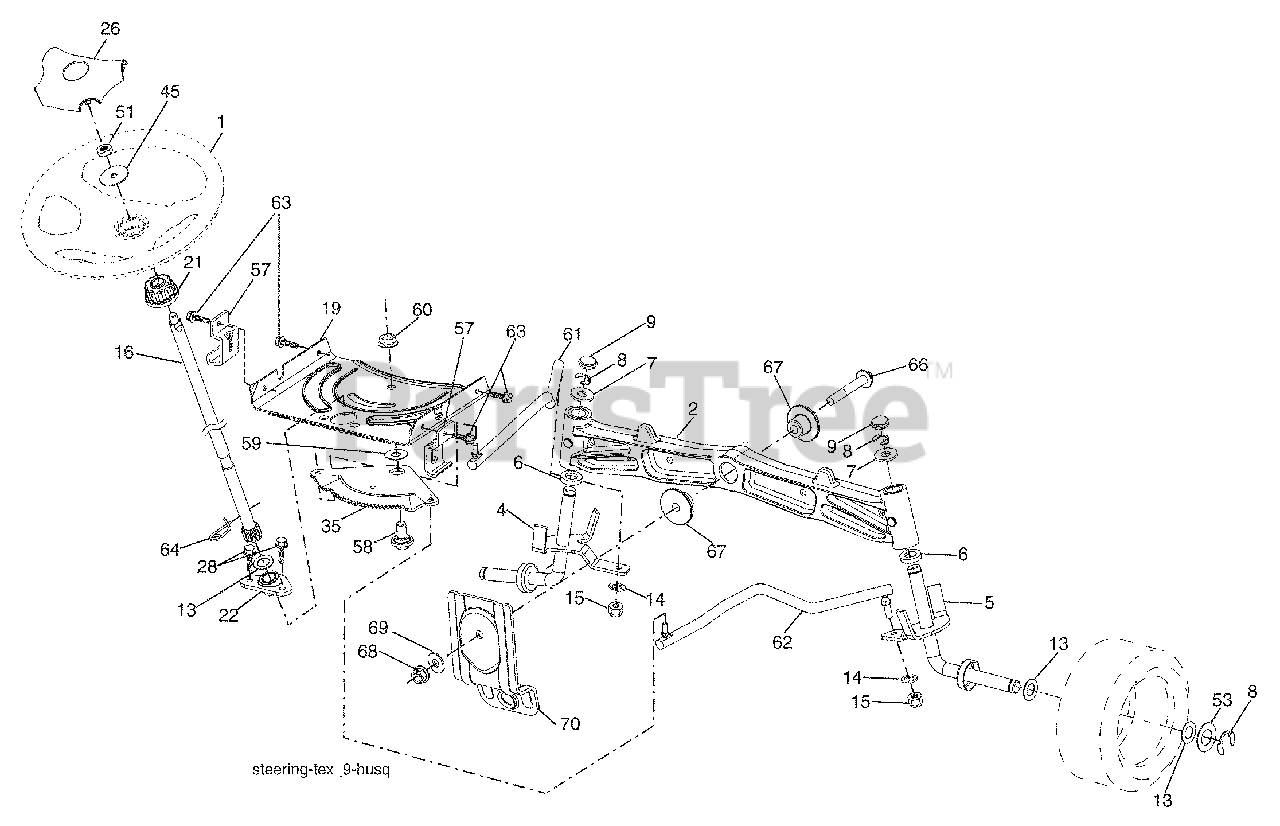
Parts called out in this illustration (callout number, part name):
1	Wheel, Steering
2	Axle Asm., Front
4	Spindle Asm., LH
5	Spindle Asm., RH
6	Bearing, Race Thrust Harden
7	Washer 25/32 x 1-5/8 x 16 Ga.
8	Ring, Klip #T5304-75
9	Cap, Spindle
13	Washer 25/32 x 1-1/4 x 16 Ga.
14	Washer, Lock Hvy Hlcl Spr 3/8
15	Nut, Crown Lock 3/8-24 unf
16	Shaft Steering
19	Plate Steering
21	Adapter, Wheel Steering
22	Bushing, Strg. Blk
26	Insert, Wheel Steering
28	Screw 3/8-16 x 3/4
35	Gear, Sector Plate
45	Washer 9/16 ID x 2-3/8 OD 12 Ga.
51	Nut Hex Jam Toplock 1/2-20 unf
53	Washer Hardened .793 x 1.637 x .060
57	Bracket Upstop
58	Bolt Shoulder Sector Pivot CFM
59	Washer Thrust Sector Steering
60	Nut Flange Lock 5/8-11
61	Draglink LH
62	Draglink, RH
63	Screw 5/16-18 x 3/4
64	Retainer Clip Spring Steering
66	Bolt Hex Fghd 7/16-14 x 3 Serr
67	Bushing PM Front Axle
68	Nut Lock Flange 7/16-14 Gr. 5
69	Washer 1.5 x .505 x .118
70	Bracket Deck Susp. Front
